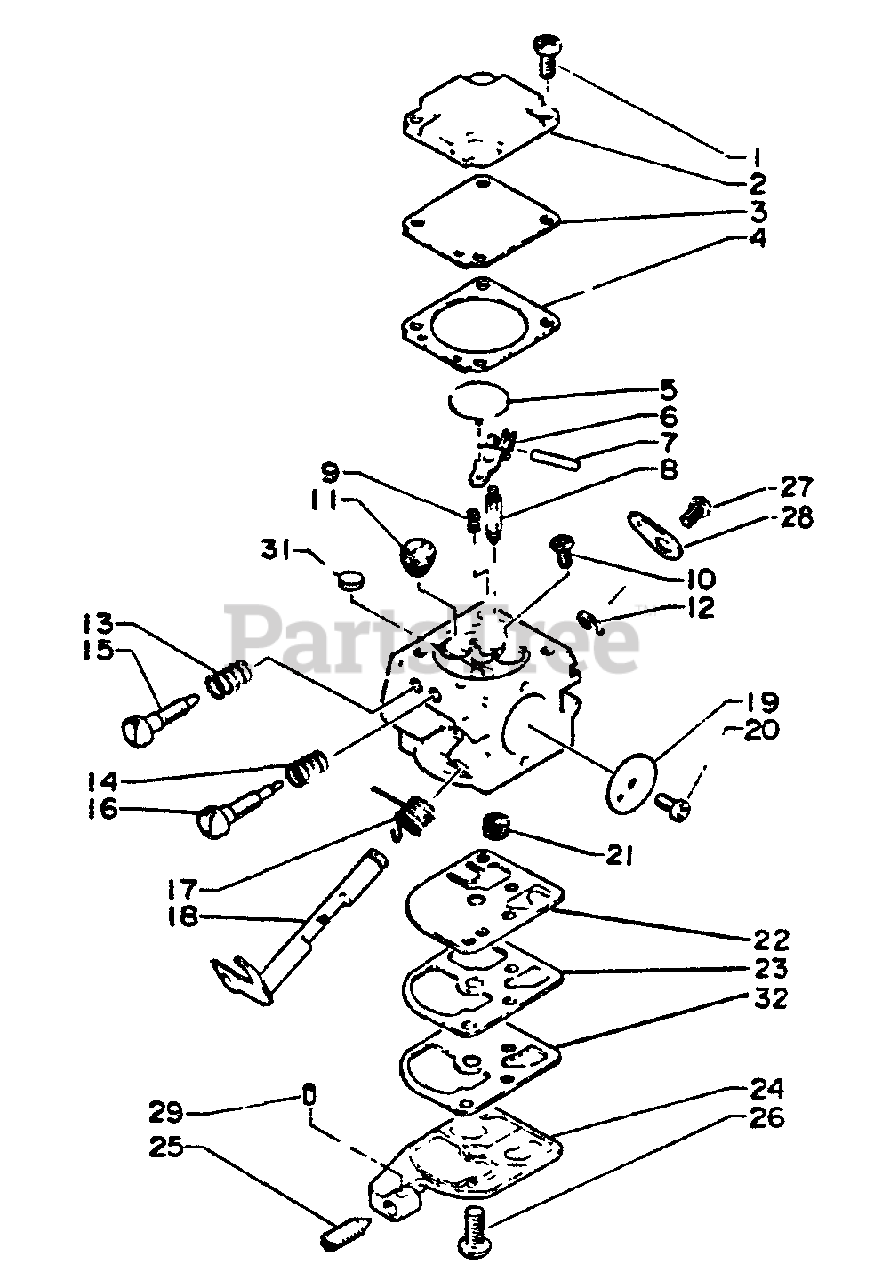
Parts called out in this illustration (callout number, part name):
1	SCREW
2	COVER, METERING
3	DIAPHRAGM
4	GASKET, METERING
5	PLUG, WELCH
6	LEVER, METERING
7	PIN, METERING LEVER
8	NEEDLE, INLET
9	SPRING, METERING LEVER
10	SCREW, METERING LEVER PIN
11	NOZZLE, CHECK VALVE
12	RING, RETAINING
13	SPRING
15	NEEDLE - HIGH SPEED
16	NEEDLE - LOW SPEED
17	SPRING, RETURN
18	SHAFT, THROTTLE
19	VALVE, THROTTLE
20	SCREW
21	STRAINER
22	DIAPHRAGM, PURGE
23	GASKET, PURGE
24	BASE, PUMP
25	SCREW, IDLE ADJUST
26	SCREW, PUMP COVER
28	LEVER, THROTTLE
29	PIECE, FRICTION
31	PLUG, WELCH
32	DIAPHRAGM, PURGE
